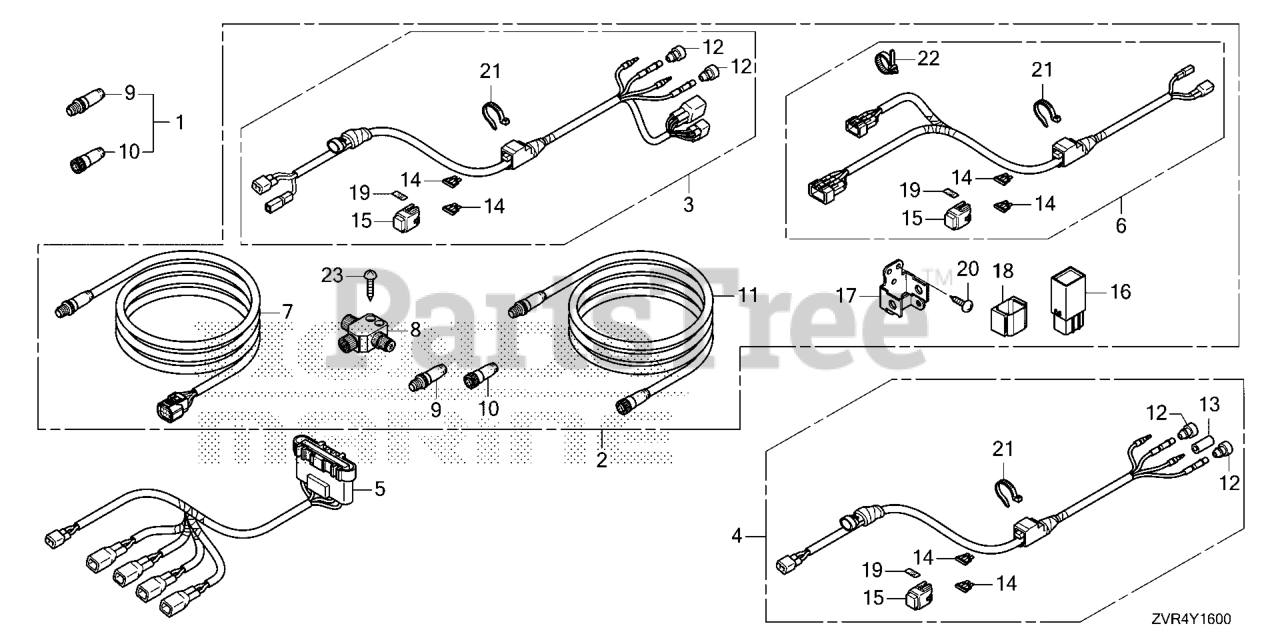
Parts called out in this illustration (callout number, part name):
1	CONNECTOR KIT, TERMINATOR
9	TERMINATOR (M)
10	TERMINATOR (F)
